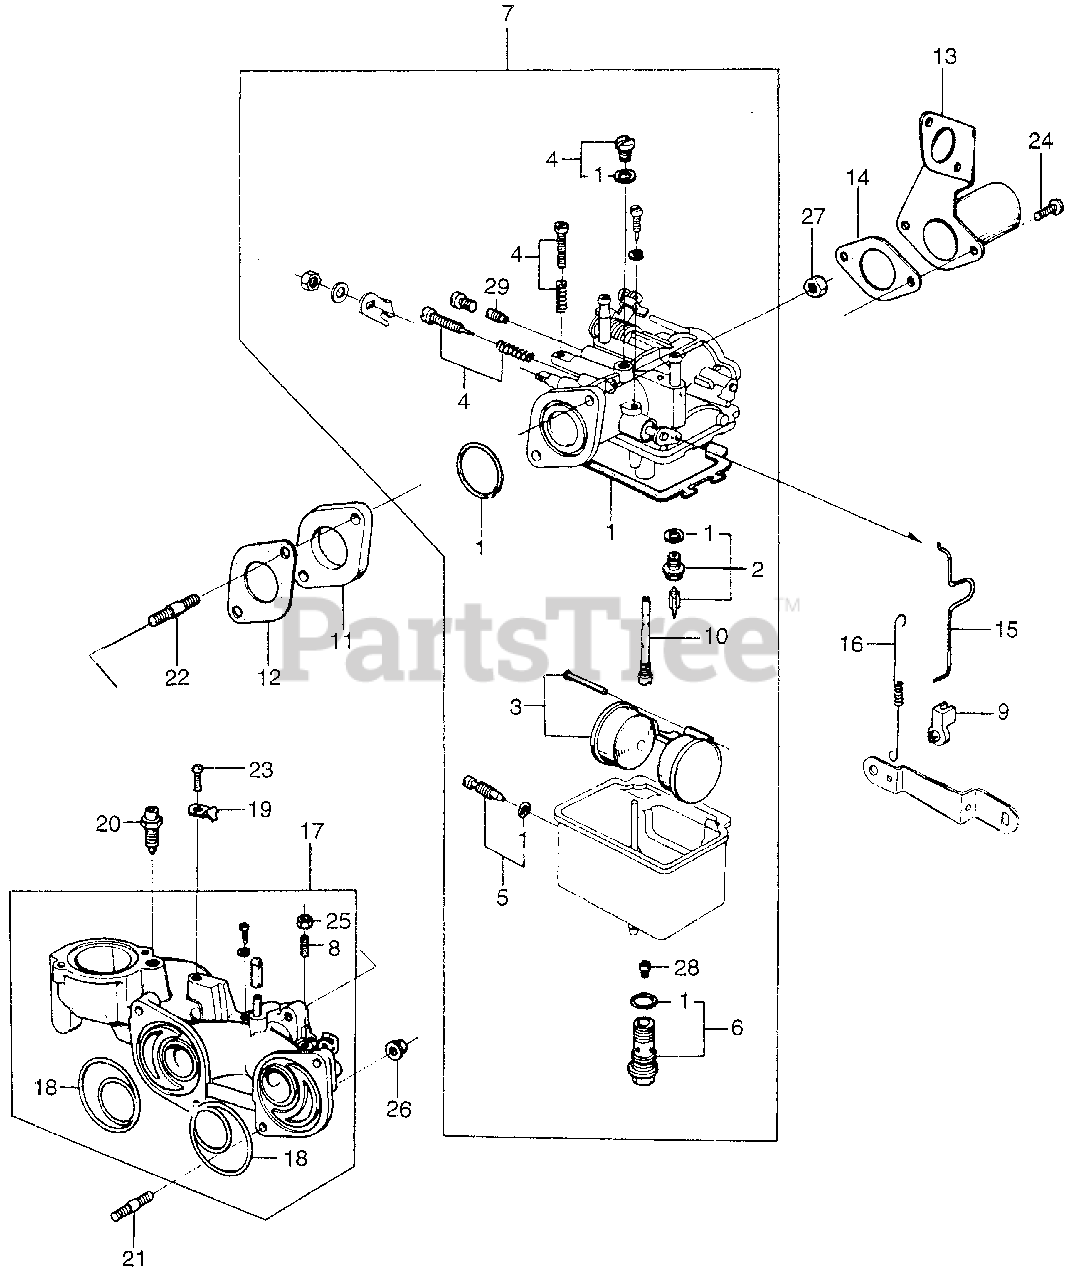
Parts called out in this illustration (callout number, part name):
1	GASKET SET (NOT AVAILABLE)
2	VALVE SET, FLOAT
4	SCREW SET A (NOT AVAILABLE)
5	SCREW SET, DRAIN
6	SCREW SET B (NOT AVAILABLE)
7	CARBURETOR ASSY. (NOT AVAILABLE)
8	SCREW, STOP
9	HOLDER, ROD (2MM) (NOT AVAILABLE)
10	NOZZLE, MAIN (NOT AVAILABLE)
11	INSULATOR, CARBURETOR
12	GASKET, INSULATOR
13	FUNNEL, AIR
14	GASKET, AIR FUNNEL
15	ROD, GOVERNOR (NOT AVAILABLE)
16	SPRING, GOVERNOR ROD (NOT AVAILABLE)
17	MANIFOLD ASSY., IN. (NOT AVAILABLE)
18	GASKET, IN. MANIFOLD
19	HOLDER, CHOKE CABLE
20	BOLT, BREATHING WATER
21	BOLT, STUD (6X37)
22	BOLT, STUD (8X40)
24	SCREW, PAN (6X10)
25	NUT, HEX. (4MM)
26	NUT, HEX. (6MM)
27	NUT, HEX. (8MM)
28	JET, MAIN (#80)
28	JET, MAIN (#82)
28	JET, MAIN (#85)
28	JET, MAIN (#88)
28	JET, MAIN (#90)
29	JET, PILOT (#40)
29	JET, PILOT (#42)
29	JET, PILOT (#45) (STD)
29	JET, PILOT (#48)
29	JET, PILOT (#50)
NI	SCREW, PAN (5X12)
